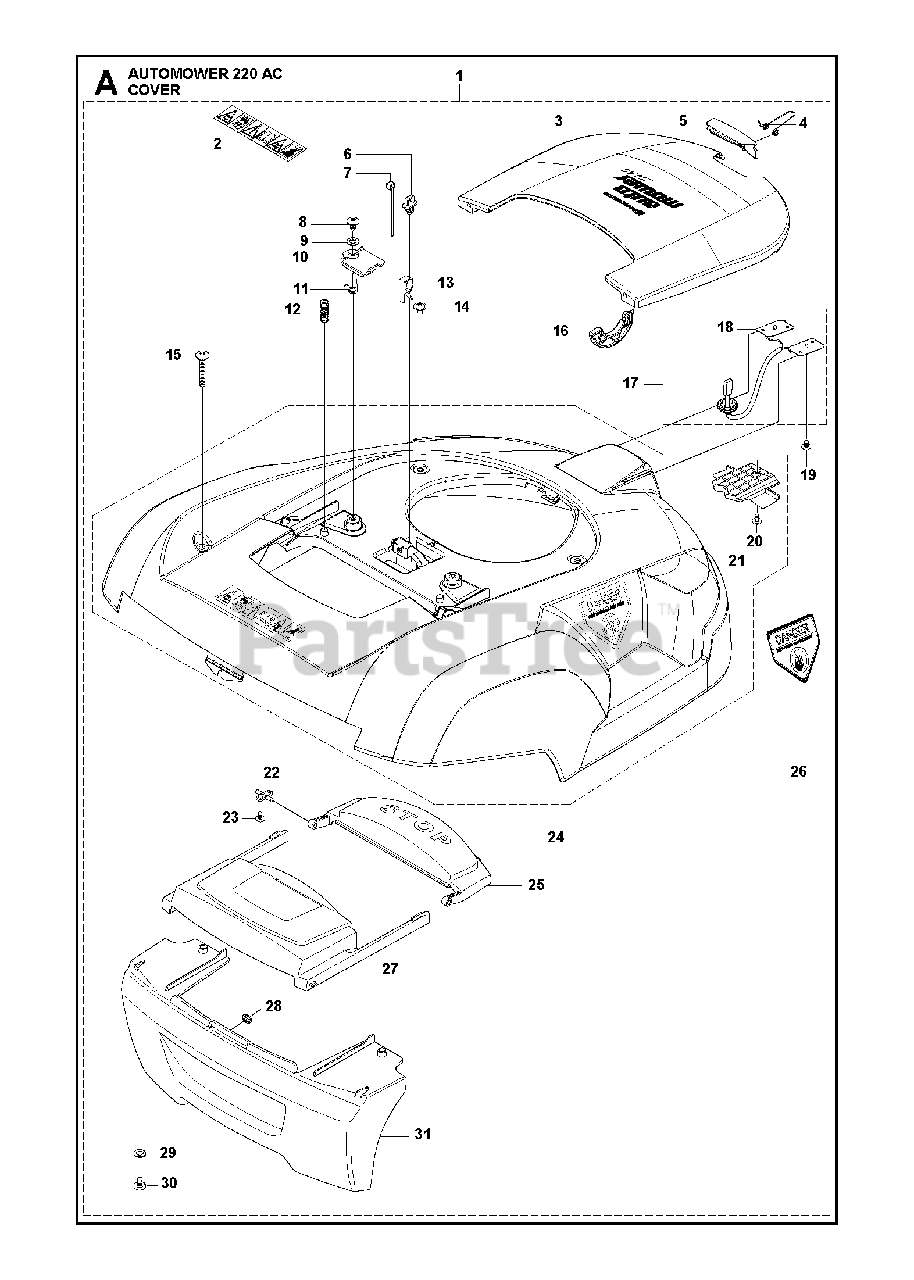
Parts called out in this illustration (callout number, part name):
1	BODY KIT FOREST GREEN
2	LABEL WARNING
5	HEIGHT ADJ. COVER LATCH
6	BRACKET FOR BAND
8	SCREW SILVER 10MM
13	CLIP RETAINER
15	SCREW IHPANM
17	CABLE ASSY
18	THIN PLATE
19	SCREW WHITE 6MM
20	SCREW 12MM
21	SPACER
23	SCREW SILVER 10MM
24	BODY KIT INCLUDING NEW BODY &
26	LABEL, DANGER
30	SCREW 14MM
31	BUMPER, COVER
